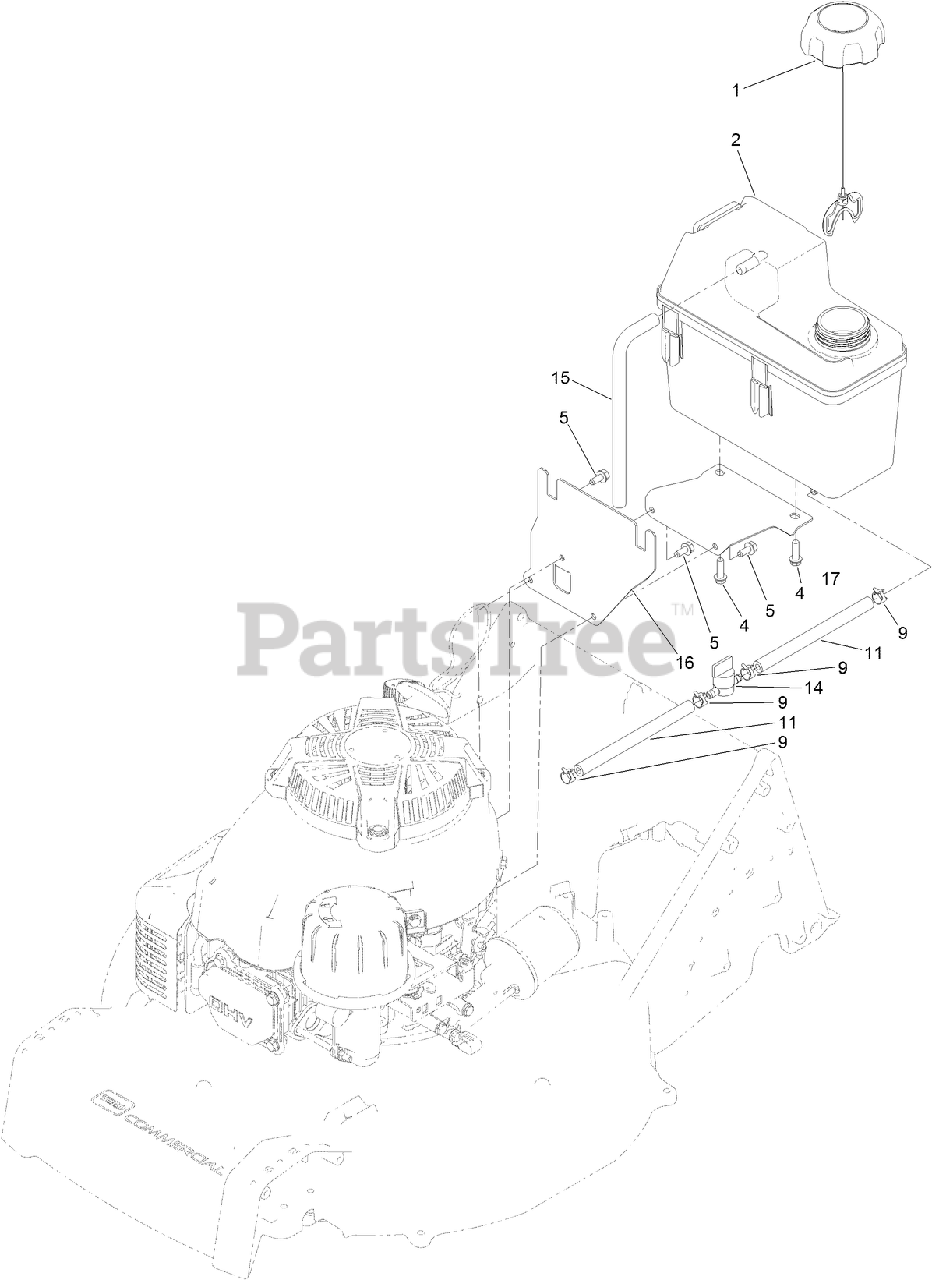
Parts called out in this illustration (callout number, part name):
2	TANK-FUEL
4	SCREW-HWH
5	SCREW-HWH
9	CLAMP-HOSE
11	HOSE-FUEL
14	VALVE-FUEL
15	HOSE-VENT, CANISTER
16	BRACKET-TANK, MOUNTING
17	BRACKET-TANK, SUPPORT
